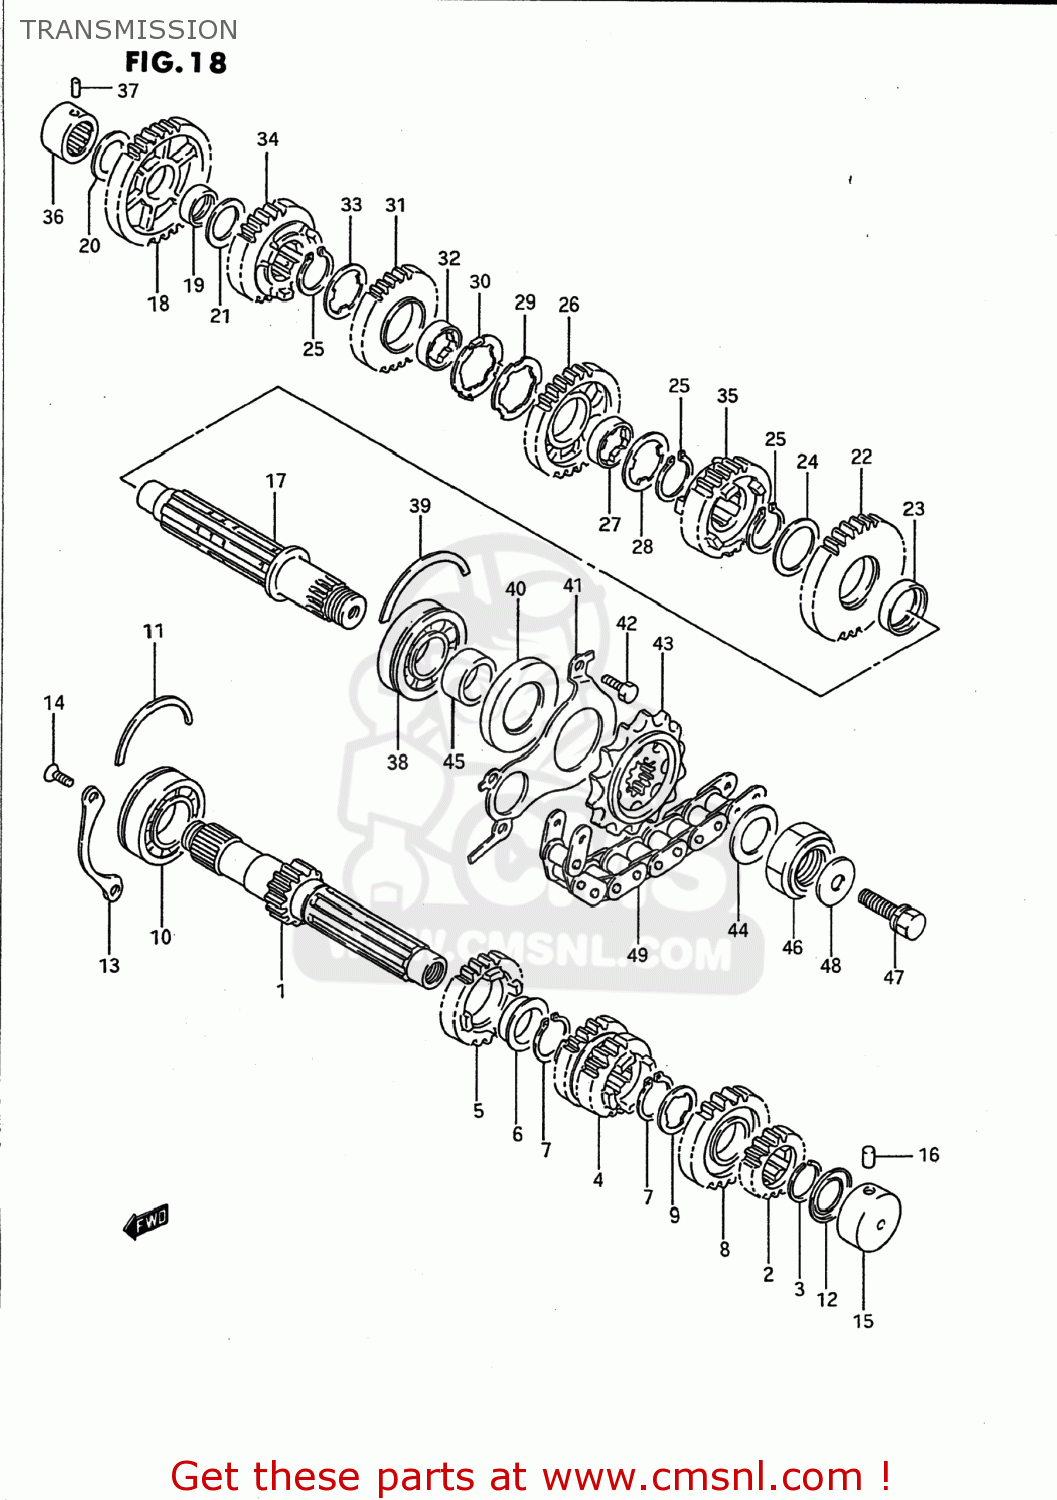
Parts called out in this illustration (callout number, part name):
1	SHAFT,COUNTER
2	GEAR,SECOND DRIVE
3	CIRCLIP
4	GEAR,THIRD & FOURTH DRIVE,N
5	GEAR,5TH DRIVE(NT:22)
6	BUSHING
7	RING,SNAP
8	GEAR,SIXTH DRIVE
9	WASHER,LOCK
10	BEARING(25X62X17)
11	C-RING
12	SEAL,OIL(20X31.2X2.7)
13	RETAINER,CNTR SHAFT BEARING
14	SCREW
15	BEARING(20X34X17.5)
16	PIN
17	SHAFT,DRIVE
18	GEAR,FIRST DRIVEN
19	BUSH(22X26X9)
20	WASHER
21	WASHER
22	GEAR,SECOND DRIVEN
23	BUSH(28X32X9.5)
24	WASHER, THRUST
25	CIRCLIP
26	GEAR,THIRD DRIVEN
27	BUSH
28	WASHER,LOCK
29	WASHER,LOCK
30	WASHER
31	GEAR,FOURTH DRIVEN
32	BUSH
33	WASHER,LOCK
34	GEAR,5TH DRIVEN(NT:27)
35	GEAR,SIXTH DRIVEN (NT:23)
36	BEARING(20X34X20)
37	PIN
38	BEARING(25X62X17)
39	C-RING
40	SEAL,OIL(34X62X6)
41	RETAINER,DRIVE SHAFT OIL SEAL
42	BOLT
43	SPROCKET,ENGINE (NT:15)
44	WASHER,THRUST
45	SPACER(25X34X17.5)
46	NUT
47	BOLT
48	WASHER
49	CHAIN ASSEMBLY,DRIVE
